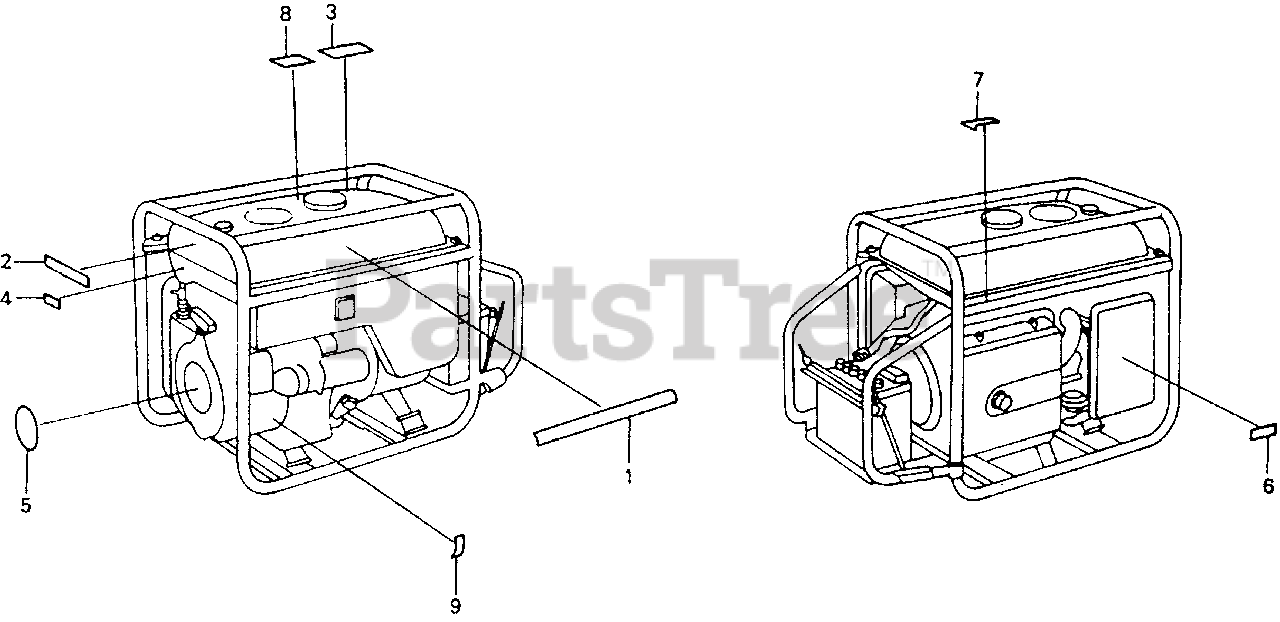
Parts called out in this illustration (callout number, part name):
1	EMBLEM (EMS4000) (NOT AVAILABLE)
2	PLATE, CAUTION (NOT AVAILABLE)
3	MARK, CAUTION (ENGLISH/FRENCH)(SPANISH)
5	LABEL, C.D.I. OIL ALERT
6	MARK, AIR CLEANER (ENGLISH)
7	MARK, EX. CAUTION (ENGLISH/FRENCH)
8	MARK, CAUTION (CO)(ENGLISH/FRENCH)(SPANISH)
9	MARK, OIL CAUTION
